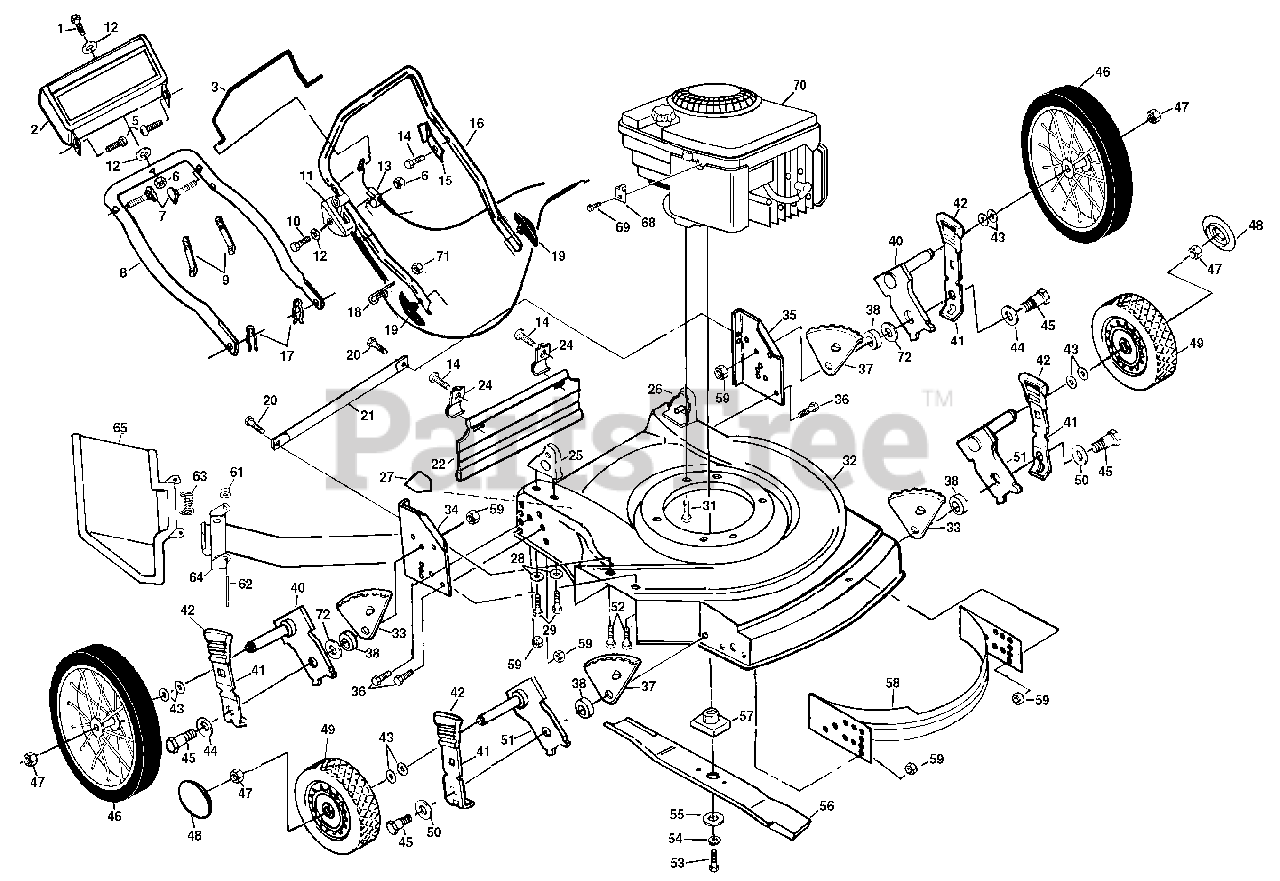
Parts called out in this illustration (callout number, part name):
1	Hex Head Washer Screw 1/4-20 x 1-1/2
2	Trim Plate
3	Control Bar
5	Self-tapping Screw #10-24 x 5/8
6	Locknut 1/4-20
7	Handle Bolt 5/16-18 x 1-3/4
8	Lower Handle
9	Wire Tie
10	Machine Screw 1/4-20 x 2-1/8
11	Throttle Control
13	Engine Zone Control Cable
14	Hex Washer Head Screw #10-24 x 1/2
15	Up-Stop Bracket
16	Upper Handle
17	Hairpin Cotter
18	Rope Guide
19	Handle Knob
20	Self-tapping Screw 1/4-20 x 1/2
21	Support Rod
22	Rear Skirt
24	Skirt Bracket
25	Handle Bracket Assembly (Right)
26	Handle Bracket Assembly (Left)
27	Danger Decal
29	Thread Cutting Screw 5/16-18 x 1-3/4
31	Thread Rolling Screw 3/8-16 x 1
32	Lawn Mower Housing
33	Wheel Adjusting Bracket (LF/RR)
34	Wheel Support Bracket (Right)
35	Wheel Support Bracket (Left)
36	Hex Head Bolt 3/8-16 x 3/4
37	Wheel Adjusting Bracket (RF/LR)
38	Spacer
40	Axle Arm Assembly (Rear)
41	Selector Spring
42	Selector Knob
43	Washer
44	Washer
45	Shoulder Bolt 3/8-16
46	Wheel & Tire Assembly 14.0 x 2.0
47	Locknut
49	Wheel & Tire Assembly 8.0 x 2.0
51	Axle Arm Assembly (Front)
52	Hex W/Sems 1/4-20 3/8 Screw
53	Hex Head Screw 3/8-24 x 1-3/8 Gr. 8
54	Helical Washer 3/8
55	Hardened Washer
56	22" Blade
57	Blade Adapter
58	Front Baffle & Rear
59	Locknut 3/8-16
62	Hinge Rod
63	Torsion Spring
64	Housing Bracket Assembly
65	Discharge Guard
68	Cable Clamp
69	Thread Rolling Screw #10-32 x 5/8
71	Locknut, Keps 1/4-20
72	Flat Washer 3/8
